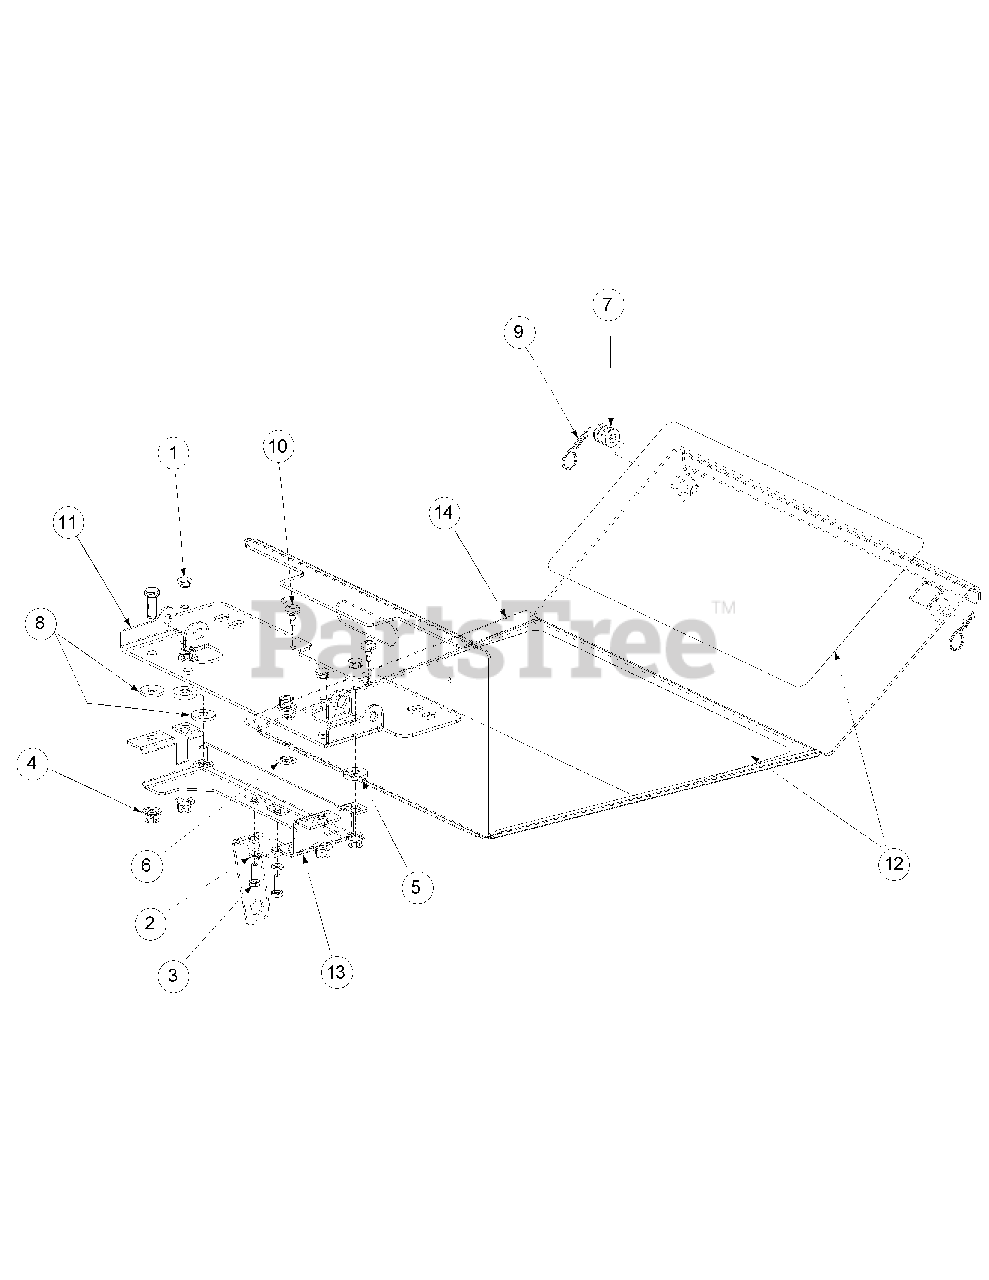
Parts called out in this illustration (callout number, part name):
1	Hex Cap Screw, 3/8-16, x 1
2	Lock Washer, 1/4
3	Hex Cap Screw, 1/4-20, .75
4	Hex Nut, Flange Lock, 3/8-16
5	Washer
6	Carriage Bolt, 3/8-16 x .75 Long
7	Flat Washer, 3/8
8	Flat Washer, .406 ID, 1.0 OD, .105
9	Hair Pin
10	Rubber Bumper, .62 OD x .22 Thick
11	Panel Seat
12	Foot Abrasive Pad
13	Support, Seat Bracket
14	Floor Panel Assembly
